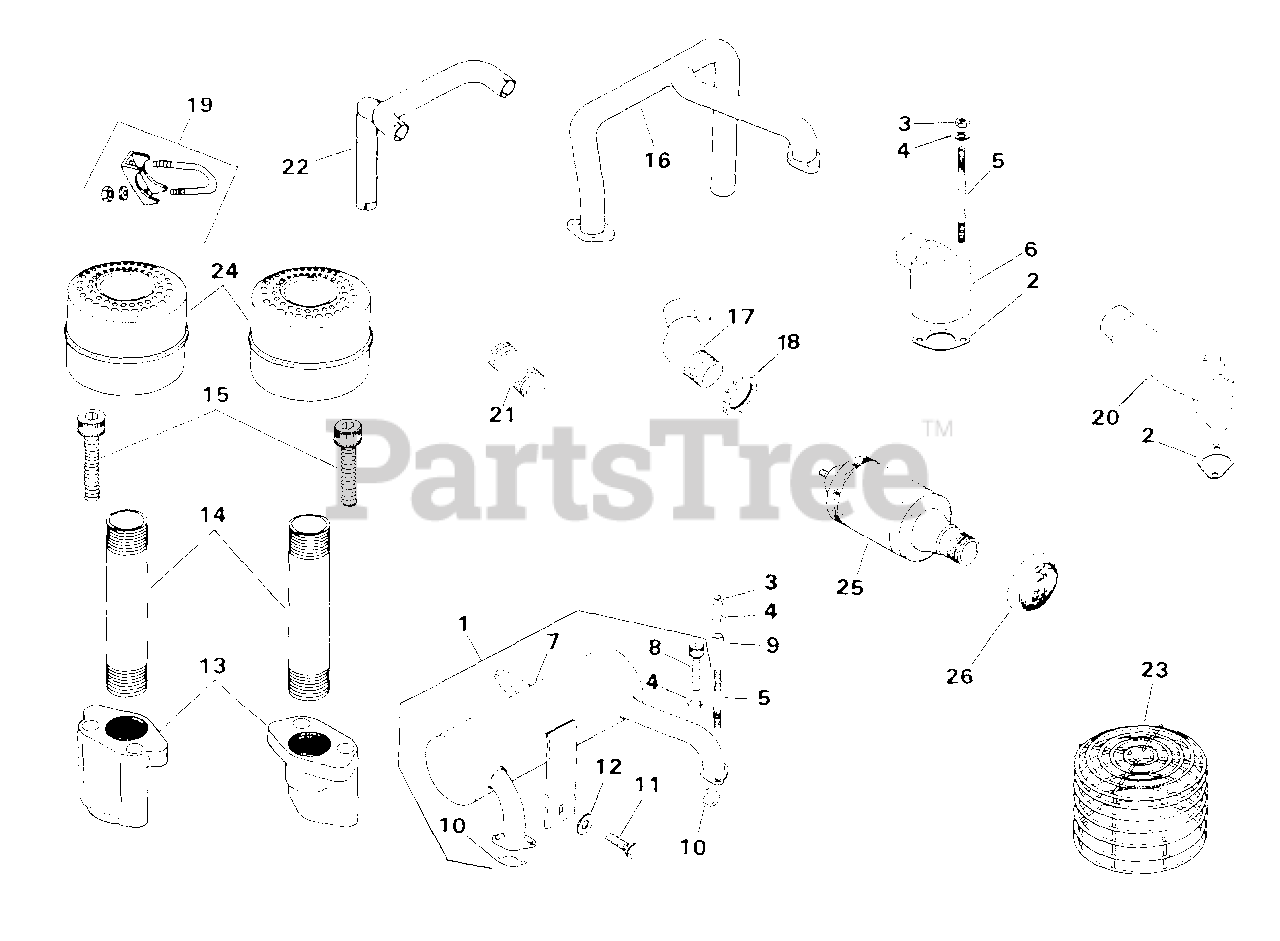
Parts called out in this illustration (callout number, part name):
2	GASKET - USE 52 041 14
3	NUT, 5/16-18 GRADE 5 USE 25 100 22-S
4	WASHER, SPRING LOCK 5/16"
5	STUD
6	MANIFOLD
7	MUFFLER
19	CLAMP, MUFFLER-USE 24 237 13-S
20	MANIFOLD - (#DSC)
